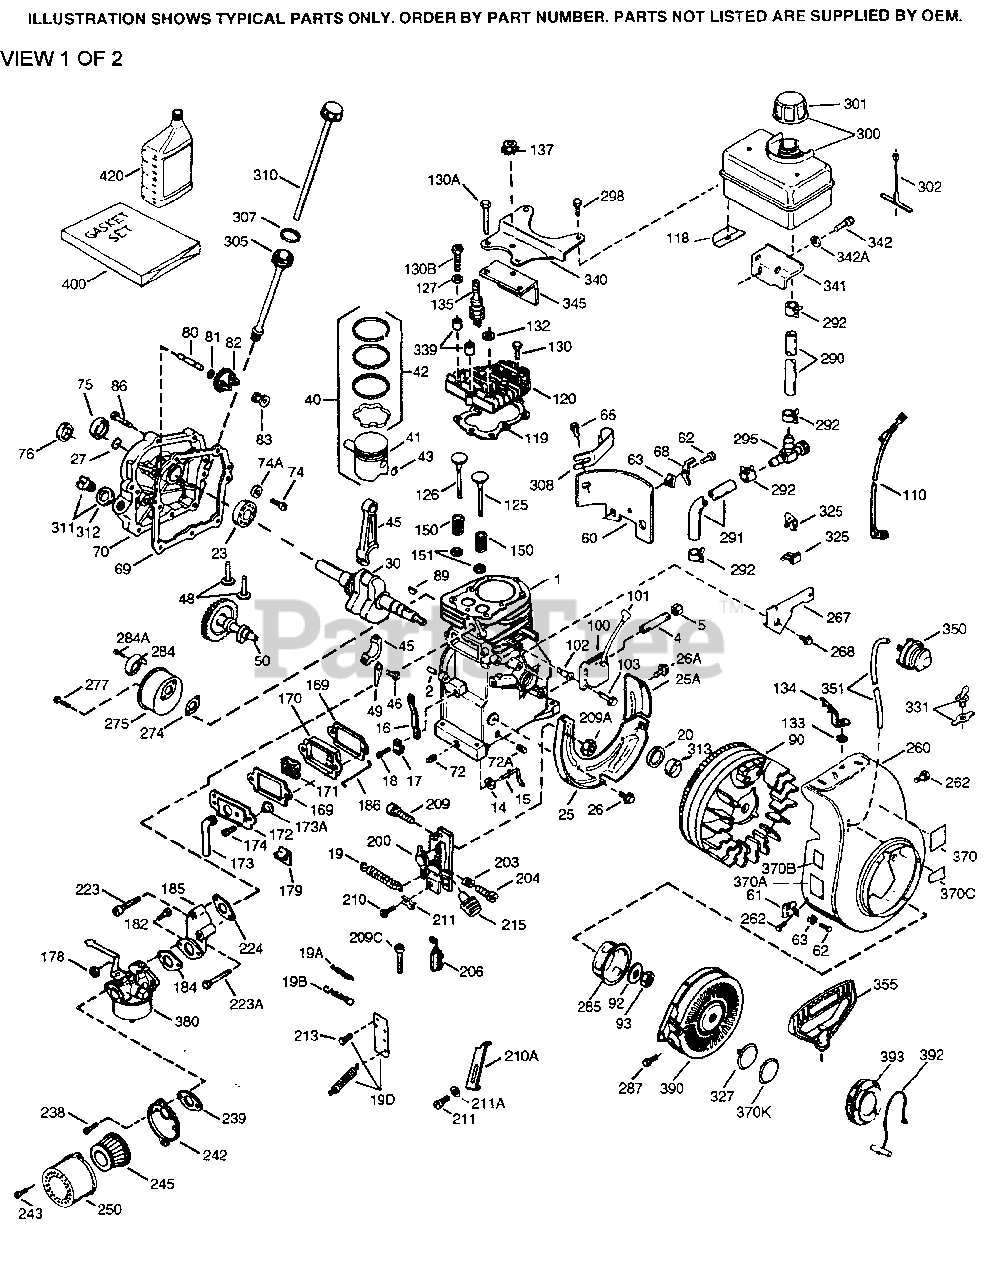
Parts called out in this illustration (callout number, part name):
1	"Cylinder (Incl. 2, 20 & 72)
2	Dowel Pin
14	Flat Washer
15	Governor Rod
16	Governor Lever
17	Governor Lever Clamp
18	Screw, 8-32 x 5/16"
19	Extension Spring
20	Oil Seal
23	Ball Bearing
25	Blower Housing Baffle
25A	Baffle Extension
26	Screw, 1/4-20 x 5/8"
27	Bearing Retainer
30	Crankshaft
40	Piston, Pin & Ring Set (Std.)
40	Piston, Pin & Ring Set (.010" OS)
40	Piston, Pin & Ring Set (.020" OS)
41	Piston & Pin Ass'y. (Std.) (Incl. 43)
41	Piston & Pin Ass'y. (.010" OS) Incl. 43
41	Piston & Pin Ass'y. (.020" OS) Incl. 43
42	Ring Set (Std.)
42	Ring Set (.010" OS)
42	Ring Set (.020" OS)
43	Piston Pin Retaining Ring
45	Connecting Rod Ass'y. (Incl. 46 & 49)
46	Connecting Rod Bolt
48	Valve Lifter
49	Oil Dipper
50	Camshaft (BCR)
60	Blower Housing Extension
65	Screw, 10-24 x 9/16"
69	* Cylinder Cover Gasket
70	Cylinder Cover Incl. 75 thru 83, 311 & 312
72	Oil Drain Plug (Sq. hd., 1/4-18)
75	Oil Seal
80	Governor Shaft
82	Governor Gear Ass'y. (Incl. 81)
83	Governor Spool
86	Screw, 1/4-20 x 1-1/4"
89	Flywheel Key (also available in Packa ged Part #740007B)
90	Flywheel
92	Belleville Washer
93	Flywheel Nut
100	Solid State Ignition
101	Spark Plug Cover
102	Solid State Mounting Stud
103	Screw, Torx T-15, 10-24 x 1
110	Ground Wire
119	* Cylinder Head Gasket
120	Cylinder Head (Incl. 130)
125	Exhaust Valve (Std.) (Incl. 151)
125	Exhaust Valve (1/32" OS) (Incl. 151)
126	Intake Valve (Std.) (Incl. 151)
126	Exhaust Valve (1/32" OS) (Incl. 151)
130	Screw, 5/16-18 x 2"
131	Screw, 5/16-18 x 1-1/2"
135	Resistor Spark Plug - RJ17LM
150	Valve Spring
151	Valve Spring Cap
169	* Valve Cover Gasket
170	Breather Body
171	Breather Element
172	Valve Cover
173	Breather Tube
174	Screw, 10-24 x 1/2"
178	Nut & Lock Washer 1/4-28
182	Screw, 1/4-28 x 7/8"
184	* Carburetor To Intake Pipe Gasket
185	Intake Pipe
186	Governor Link
200	Control Bracket (Incl.19,203,204,206)
203	Compression Spring
204	Screw, 5-40 x 7/16"
206	Terminal
215	Control Knob
223	Screw, 1/4-20 x 1-19/32"
223A	Screw, 1/4-20 x 1-7/32"
224	* Intake Pipe Gasket
238	Screw, 10-32 x 1/2"
239	* Air Cleaner Gasket
242	Air Cleaner Base
243	Screw, 8-32 x 3/8"
245	Air Filter
250	Air Cleaner Cover
260	Blower Housing
262	Screw, 1/4-28 x 7/16"
267	Hold Down Bracket
275	Muffler (Incl. 277)
277	Screw, 1/4-20 x 2-1/4"
287	Screw, 8-32 x 21/64"
290	Fuel Line
292	Fuel Line Clamp
298	Screw, 1/4-15 x 7/8"
300	Fuel Tank (Incl. 292 & 301) (2 Quart)
301	Fuel Cap (Red)
311	Oil Fill Plug (Incl. 312) also availa ble in Packaged Part #740079
312	* Oil Fill Plug Gasket
340	Fuel Tank Bracket
342	Screw, 1/4-20 x 7/16"
345	Heat Baffle
370	Name Decal
370	Lubrication Decal
370	Throttle Decal
380	Carburetor (Incl. 184)
392	Starter Rope
393	Starter Pulley
400	* Gasket Set (Incl. items marked PK in notes) Incl. part #'s 26754A (1), 267 56 (1), 27234A (2), 27272A (1), 27677 A (1), 29673 (2), 29953C (1), 30081A (1), 31340A (1), 31619A (1), 31688A ( 2), 32649A (1), 33170A (1)
420	SAE 30 4-Cycle Engine Oil (Quart)
